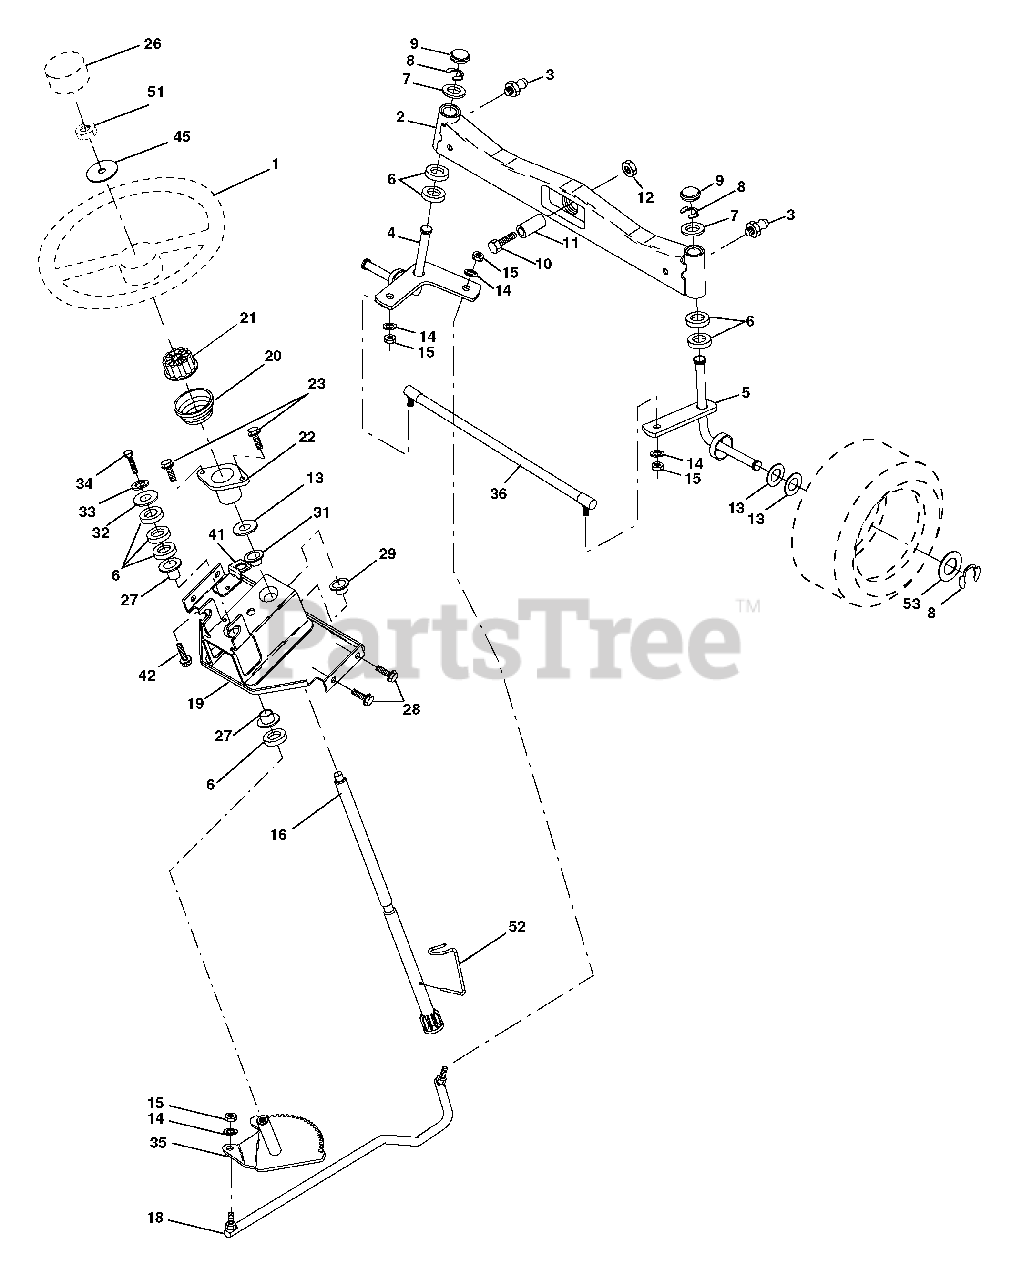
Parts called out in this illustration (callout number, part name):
1	Wheel, Steering
2	Axle Asm., Front
3	Fitting, Grease
4	Spindle Asm, LH
5	Spindle Asm., RH
6	Bearing, Race Thrust Harden
7	Washer 25/32 x 1-5/8 x 16 Ga.
8	Ring, Klip #T5304-75
9	Cap, Spindle
10	Bolt, Fin Hex 5/8-11 x 2-3/4
11	Spacer Brg Axle Front 1.570
12	Nut, Lock Flange 5/8-11 unc
13	Washer 25/32 x 1-1/4 x 16 Ga.
14	Washer, Lock Hvy Hlcl Spr 3/8
15	Nut Crownlock 3/8-24
16	Shaft Asm., Steering
19	Support Asm., Steering Vgt
20	Boot Steering
21	Adapter, Wheel Steering
22	Bushing, Strg.
26	Cap , Wheel Steering
27	Bearing, Col. Strg.
28	Screw 3/8-16 x 3/4
29	Bearing, Flange
31	Bushing, Nyliner Snap
32	Washer 11/32 x 1 x 10 Ga.
33	Washer, Lock Hvy Hlcl Spr 5/16
34	Bolt, Hex Hd 5/16-18 x 3/4
35	Gear, Sector Steering
41	Bracket Switch Inerlock VGT97
42	Screw 5/16-18 x 1/2
44	Extension Steering Premium
45	Washer 9/16 ID x 2-3/8 OD 12 Ga.
51	Nut Hex Jam Toplock 1/2-20 unf
52	Clip Steering
53	Washer Hardened
